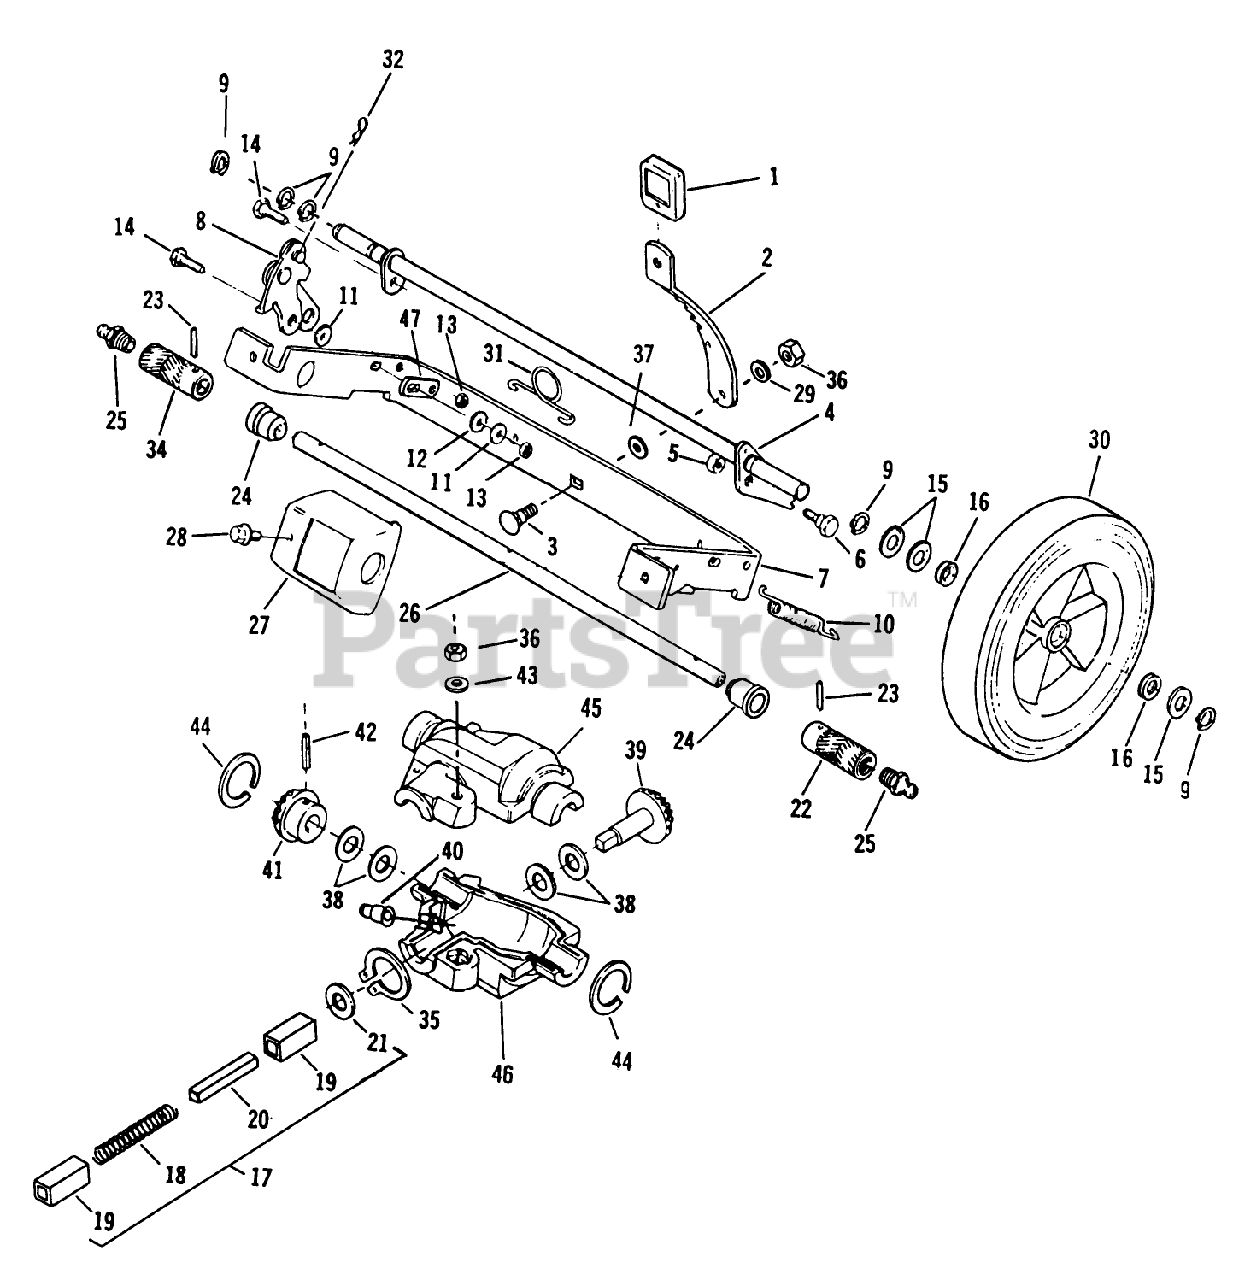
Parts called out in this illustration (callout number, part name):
2	LEVER
5	LOCKNUT E
6	BOLT RB&W
7	BRACKET *GREEN
8	CLUTCH AY ARGO
9	RET RING
10	SPRING
11	WASHER S
13	STOP NUT
14	BOLT RB&W
15	SPACER
16	WASHER
18	SPRING
19	BUSHING BKWY
21	THRUST WASHER
22	ROLLER (LEFT) VS
22	ROLLER-LH
23	PIN
24	SLEEVE &BEARING AY
25	GREASE FITTING AP
26	DRIVE SHFT TAG AY
29	WASHER S
30	WHEEL & TIRE KIT
31	SPRING N.A.S
34	ROLLER (RIGHT) VS
34	ROLLER-RH
36	LOCKNUT E
37	WASHER SPRING LAR
38	THRUST WASHER
39	GEAR BEST
40	ZERK FITTING
41	GEAR ADVANCE
42	ROLL PIN
43	WASHER F
